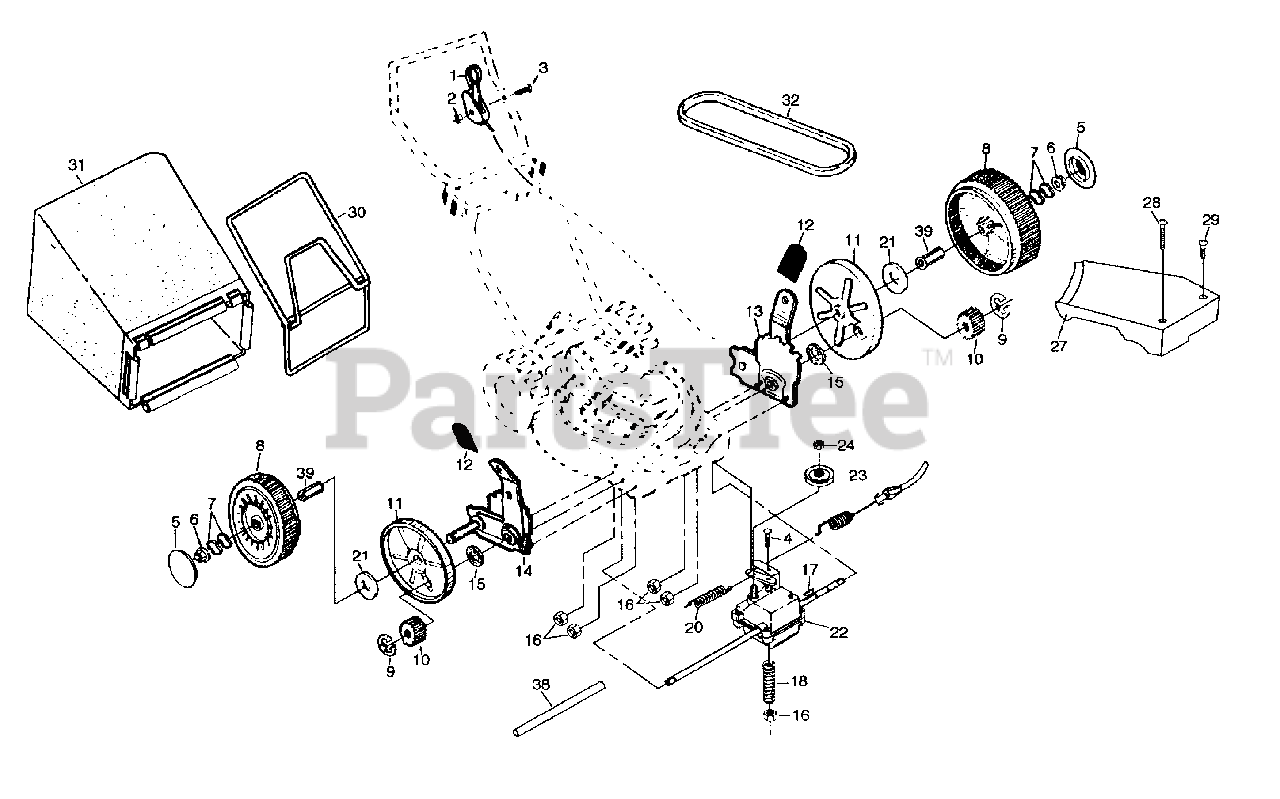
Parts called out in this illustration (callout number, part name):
1	Drive Control
2	Locknut #10-24
3	Pan Head Machine Screw 1/4-20 x 2-1/8
4	Carriage Bolt 1/4-20 x 2
6	Nut
7	Wave Washer
8	Wheel & Tire Assembly
11	Dust Cover
12	Selector Knob
13	Wheel Adjuster Assembly (Left)
14	Wheel Adjuster Assembly (Right)
15	Felt Washer
16	Locknut
17	Hi-Pro Key
21	Washer 1/2 x 1-1/2 x .134
22	Gear Case Assembly
23	Drive Pulley
24	Locknut
27	Drive Cover
28	Pan Head Tapping Screw #10-24 x 2-3/4
29	Pan Head Tapping Screw #10-24 x 1-3/4
30	Catcher Frame
31	Grass Bag
32	V-Belt
38	Drive Shaft Cover
39	Wheel Bushing
